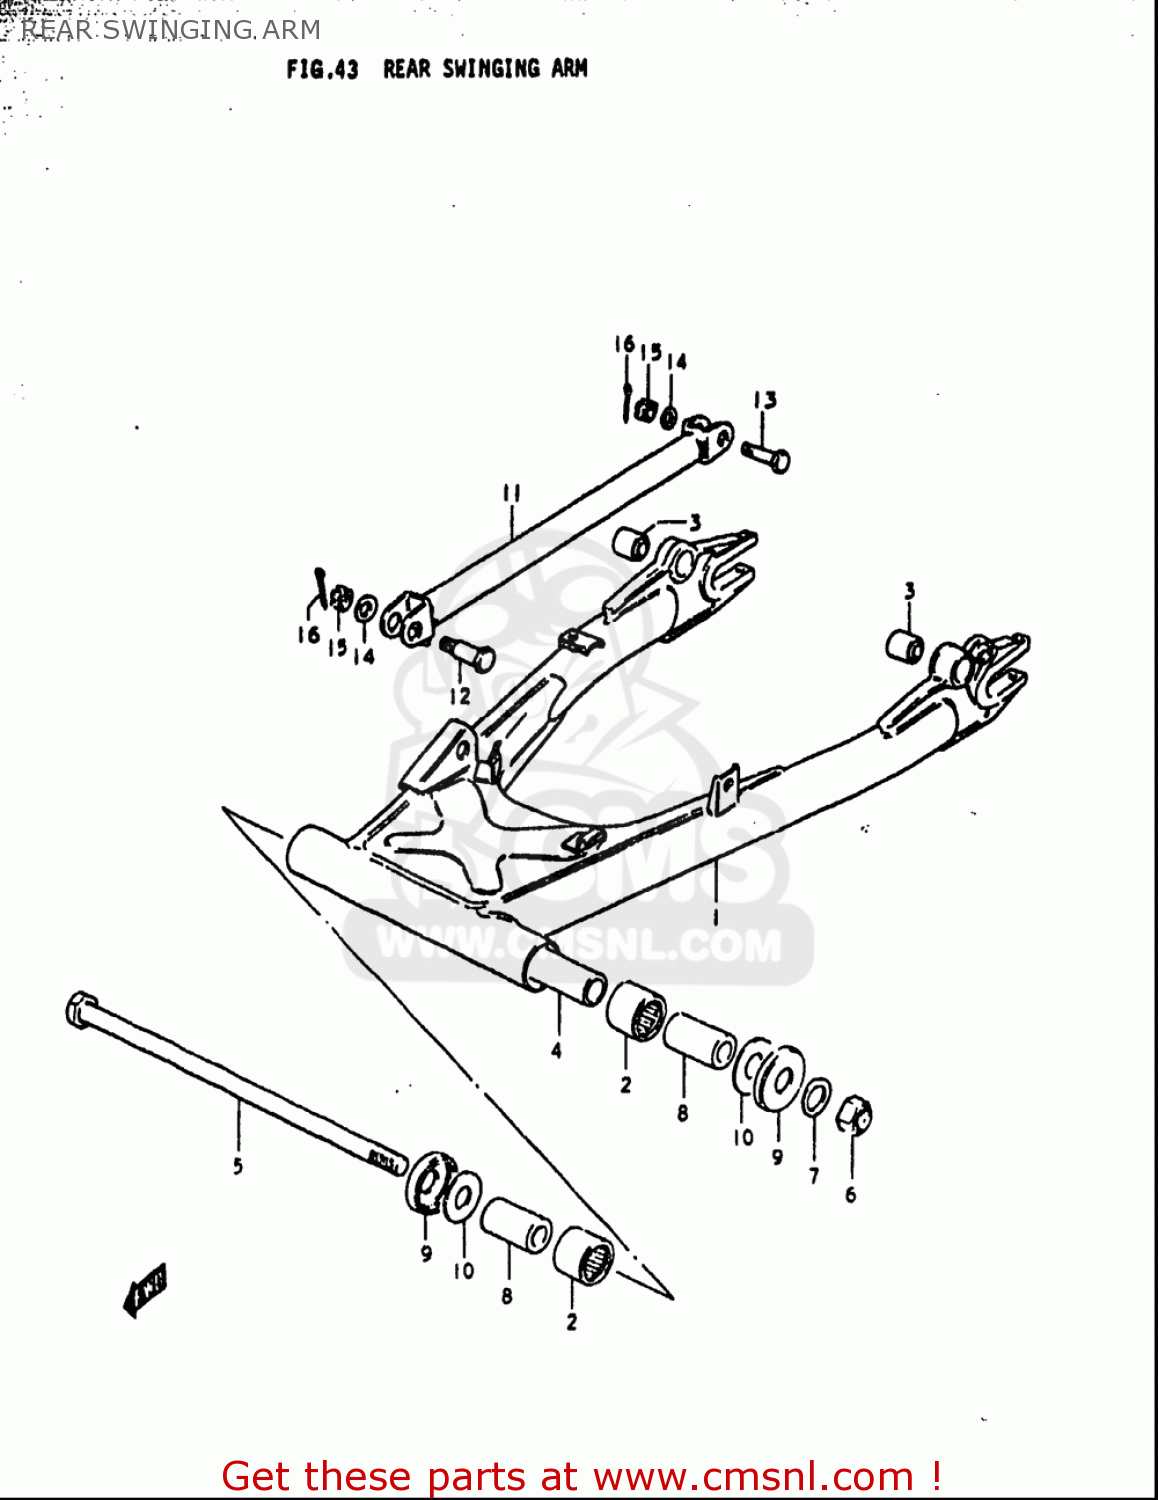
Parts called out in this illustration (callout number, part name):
2	BEARING(25X33X30)
3	BUSH
4	SPACER,RR SWGARM PIVOT CTR
5	SHAFT,RR SWINGINGARM PIVOT
6	NUT 16MM
7	WASHER
8	SPACER,RR SWGARM PIVOT
9	COVER,RR SWGARM DUST SEAL
10	WASHER
12	BOLT M10X39
13	BOLT(10X39)
14	WASHER
15	NUT
16	PIN
